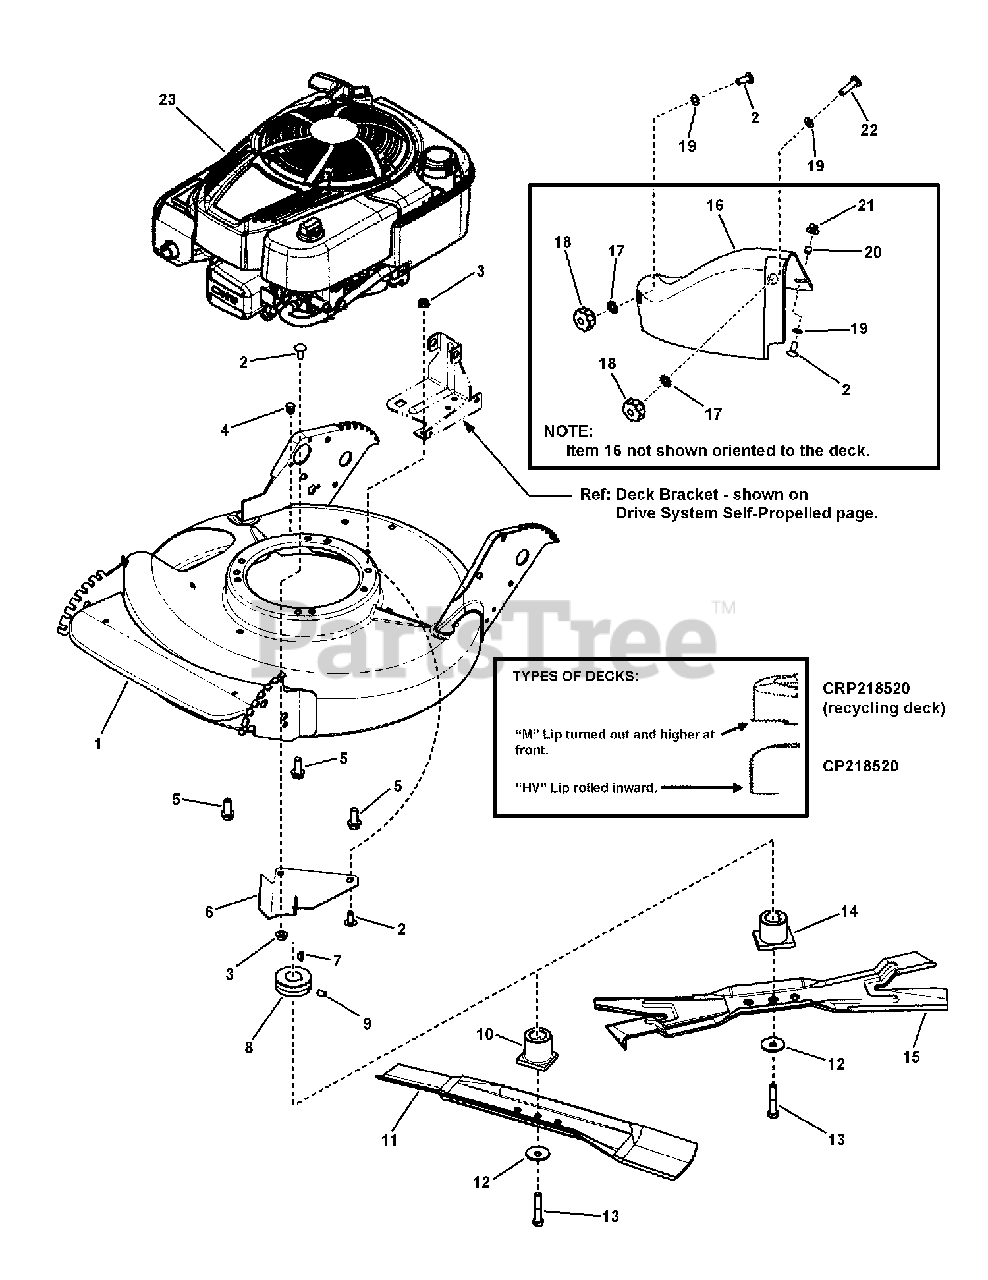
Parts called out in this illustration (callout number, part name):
1	WELDMENT, Deck, 21" Non-Adjust. Air
1	WELDMENT, Deck, 21", Self-Propelled, HV
2	BOLT, 5/16-18 x 3/4" Short Neck Carriage GR 5
3	NUT, 5/16-18 Hex Flange Lock, GR 5, YZ
4	PLUG, Hole, Polyethylene
5	SCREW, 3/8-16 x 1" Self-Tapping
6	COVER, Belt
7	KEY, Woodruff #HP-506 Hi-Pro
8	PULLEY, Engine (25mm I. D. x 2-1/8" O.D.)
9	SCREW, 5/16-18 x 1/2" Hex Socket Head
10	HUB, Blade Drive, 25MM I.D. (.9" crank to blade, 1.75" square)
11	BLADE, 21" Standard Lift
12	WASHER, Cone
13	SCREW, 3/8-24 x 2" Hex Head Cap, GR 5
14	HUB, Blade Drive, 2 Position, 25MM I.D. (1.08" crank to blade, 1.75" x 2.25")
15	BLADE, 21" Ninja
16	COVER, 21" Deck
17	WASHER, 5/16" Internal/External Lock
18	KNOB, Fluted, 5/16-18 x 1/2"
19	RETAINER, 5/16" Bolt
20	SPACER, .316 I.D. x .375 O.D. x .310 thick
21	NUT, 5/16-18 Hex Large Flange Center Lock
22	BOLT, 5/16-18 x 1-1/8 Round Head Short Square Neck, GR 5 ZP
23	* ENGINE, B&S 850 Series, W14
23	* ENGINE, B&S 850 Pro Series, W14
